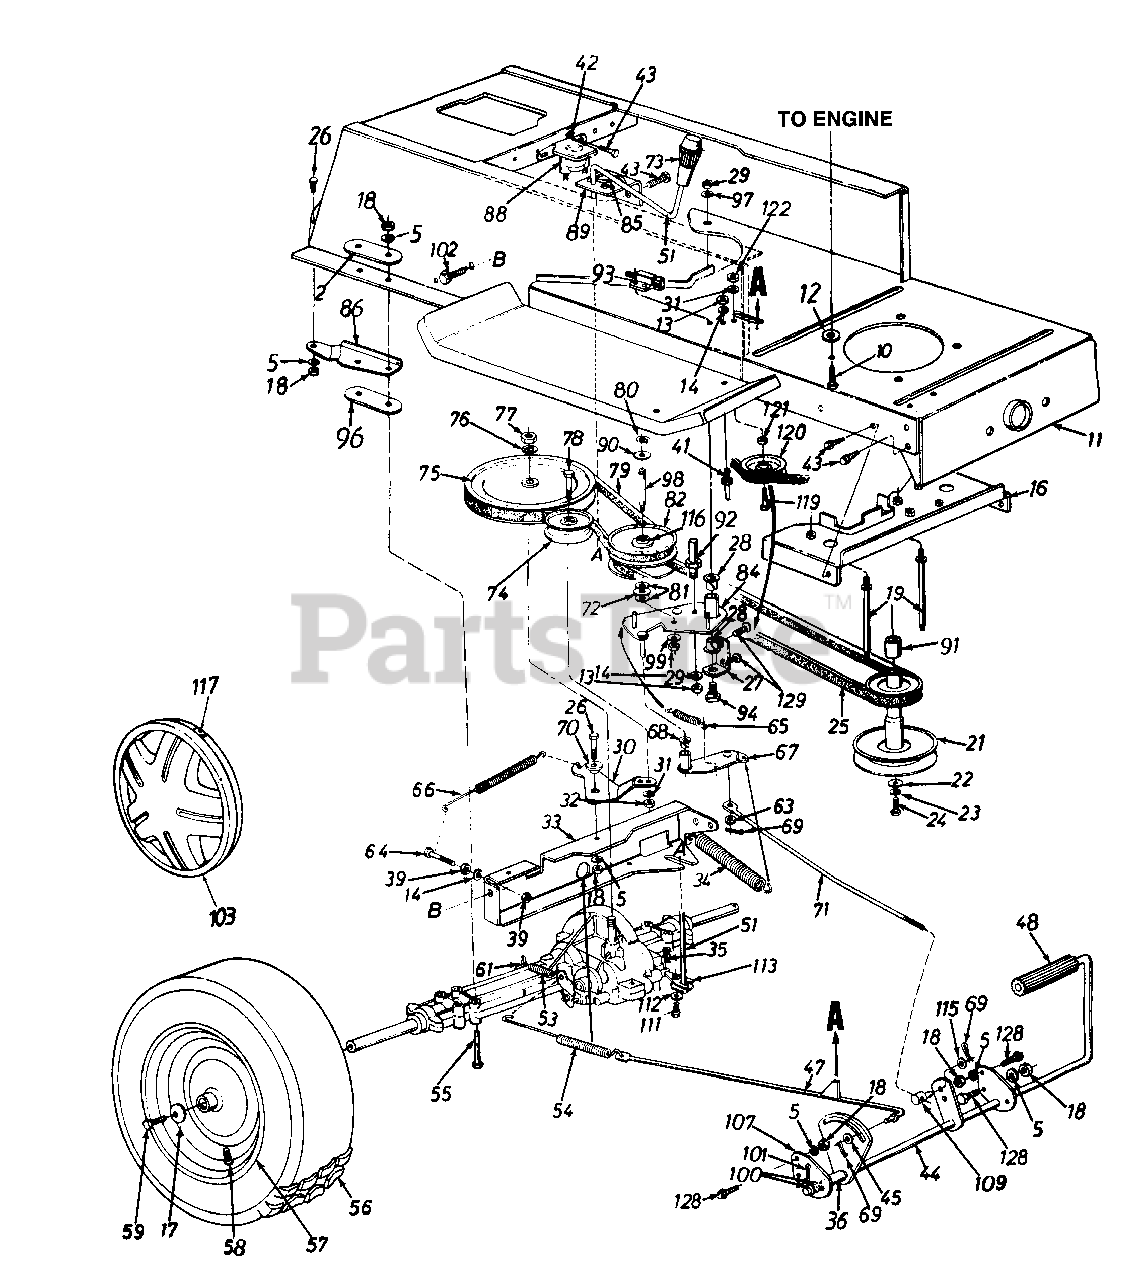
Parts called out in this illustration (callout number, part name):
5	L-Wash. 5/16" I.D.
10	Hex L-Wash. Tap Scr. 3/8-16 x 1.5" Lg. (Twin Cylinder)
14	L-Wash. 1/4" I.D.
18	Hex Nut 5/16-18 Thd.
19	Belt Guard Stud 3.6" Lg.
21	Engine Pulley
22	Fl-Wash. 7/16" I.D. x 1.25"
23	L-Wash. 7/16" I.D.
24	Hex Bolt 7/16-20 x 1.50" Lg.
25	Variable-Speed Belt
26	Hex Bolt 5/16-18 x .75" Lg.
27	Bearing Shaft Bracket Ass'y.
28	Flanged Nyliner Brg. 5/8" I.D. x .88" Lg.
29	Hex Nut 3/8-24 Thd.
31	L-Wash. 3/8" I.D.
32	Hex Nut 3/8-24 Thd.
35	Inter. Cotter Pin
36	Spacer .63" I.D.
39	Hex Nut 1/4-28 Thd.
40	Hex AB-Tap Scr. 1/4" x .62" Lg.
41	Belt Guard Pin
42	Ext. L-Wash. 1/4" I.D.
43	Hex Wash. Hd. S-Tap Scr. 1/4-20 x .50" Lg.
47	Brake Rod Ass'y.
48	Foot Pad
51	Shift Lever Ass'y.
53	Ext. Spring .38" O.D. x 2.5"
54	Ext. Spring .59" O.D. x 7.08"
55	Hex Bolt 5/16-18 x 3.5" Lg.
56	Wheel Ass'y. Comp.
57	Wheel Rim Only
58	Air Valve
59	Hex Bolt 5/16-24 x .75" Lg.
61	Brake Return Spring Anchor
63	Fl-Wash. .34" I.D. x .68" O.D.
64	Hex Bolt 1/4-28 x 1.25" Lg.
65	Ext. Spring
66	Ext. Spring .62" O.D. x 6.12"
68	Flanged Bearing
69	Cotter Pin 3/32" Dia.
70	Shoulder Spacer .27" Lg.
71	Speed Control Link
72	Truss Bearing .56 Dia. x 1.25"
73	Shift Knob
74	Fl-Idler Pulley 3.25" x .75"
75	"V" Pulley
76	Bell-Wash. .56" I.D. x 1.125"
77	Hex Jam Nut 5/16-18 Thd.
78	Hex Bolt 3/8-24 x 1.75" Lg.
79	Variable Speed Belt
80	Snap Ring .56" Dia.
81	Fl-Wash.
82	Variable Speed Pulley Ass'y. 5" O.D.
90	Teflon Washer .565" I.D.
91	Spacer 1" I.D. x 1.25" Lg.
92	Belt Keeper 3" Lg.
93	Safety Switch (Clutch)
94	Shld. Bolt 3/8-24 x 3.12" Lg.
96	Transaxle Spacer
97	Bell-Wash. .38" I.D. x .88"
98	Shaft .56" Dia. x 3.875" Lg.
99	Bell-Wash. .39" I.D. x 1.12"
100	Fl-Wash. .64" I.D. x .94"
101	Cotter Pin 1/8" Dia. x 1.25"
102	Hex Wash. Hd. Scr. 5/16-18 x .62" Lg.
103	Hub Cap (Gray)
111	Hex Bolt 1/4-28 x .50" Lg.
112	Bell-Wash. .265" I.D. x .75"
113	Shift Lever Link Ass'y.
115	Fl-Wash. .385" I.D. x .62"
116	Needle Brgs.
117	Spring Clip
119	Hex Bolt 3/8-16 x 1.25" Lg.
120	Fl-Idler w/Flanges 2.75" O.D.
121	Fl-Wash. .39" I.D. x 1.12" O.D.
122	Hex Nut 3/8-16 Thd.
128	Hex Wash. TT-Tap Scr. 5/16-18 x .75" Lg.
129	Hex Wash. AB-Tap Scr. 5/16-18 x .75" Lg.
